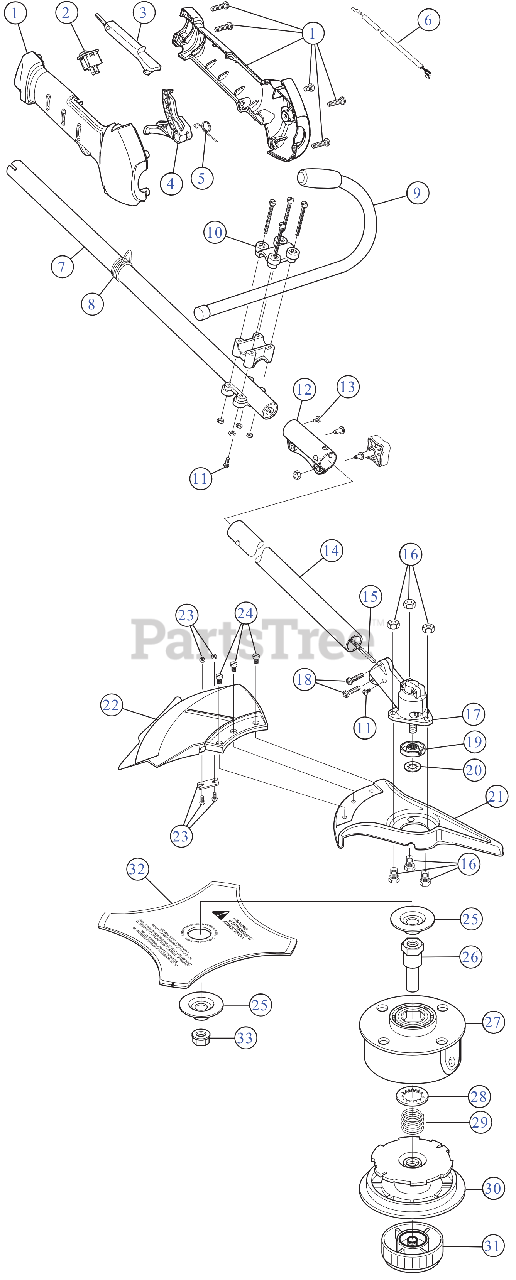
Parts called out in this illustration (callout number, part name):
1	THROTTLE GRIP ASSEMBLY
2	SW, MOMENTARY ON/O
3	LOCK OUT LEVER RED
4	THROTTLE TRIGGER
5	SPRING TRIG
6	THROTTLE CABLE
7	UPPER DRIVE SHAFT HOUSING ASSEMBLY
8	CLAMP-SHOULDER STR
9	HANDLE ASSEMBLY-JAY
10	HANDLE BRACKET ASSEMBLY
11	SCREW, 8-32 x .312 P
12	SPLIT BOOM COUPLER KIT
13	SCREW, 10-32X.250 TA
14	OUTER DRIVE HOUSING
15	LOWERIBLE DRIVE SHAFT
16	SCREW SET-GUARD MT
17	GEARBOX ASSEMBLY
19	SPACER-GEARBOX
20	PALNUT:3/8" DIAM
21	SHIELD-BLADE CAST
22	GUARD ASSEMBLY BRUSH CUT
23	BLADE ASSEMBLY
24	SCREW-GUARD MTG PK
25	WASHER-BLADE CLAMP BRUSH CUT
26	SHAFT-SPOOL
27	SPOOL ASSEMBLY-OUTER
28	RETAINER .968 OD
29	SPRING-SPOOL
30	REEL-INNER SPOOL 3000 STRG TRM
31	KNOB ASSEMBLY-BUMP 3000 STRG TRM
32	BLADE 4-TOOTH
33	BLADE LOCK NUT
